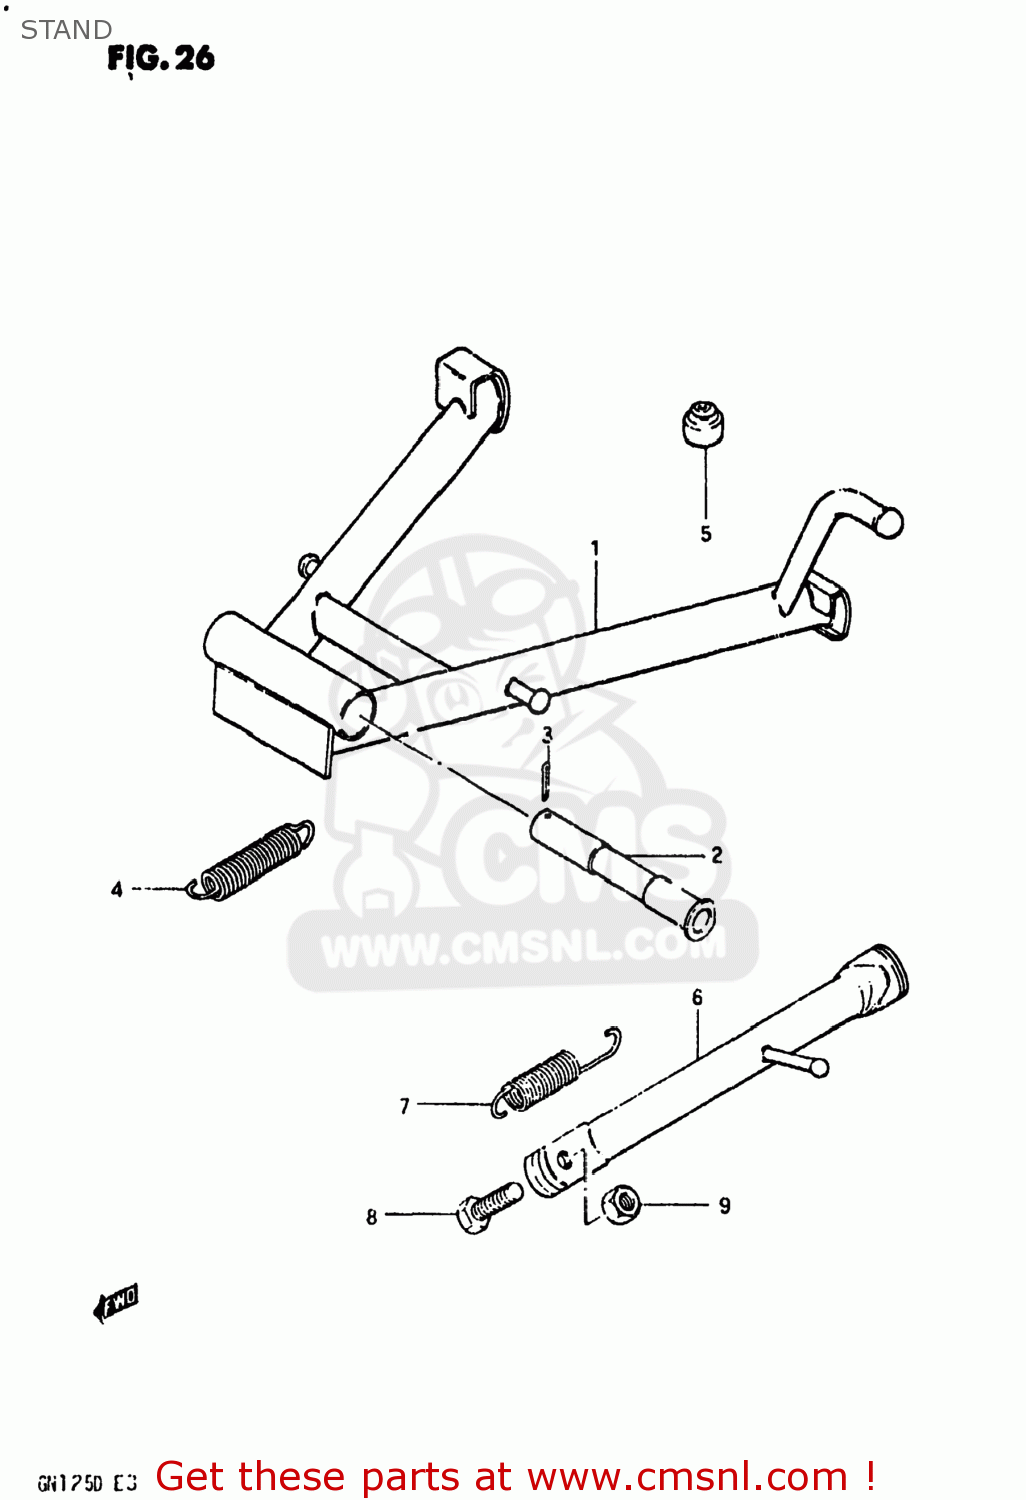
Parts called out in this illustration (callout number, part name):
1	STAND,CTR
2	SHAFT,CENTER STAND
3	COTTER PIN
4	SPRING
5	CUSHION
6	STAND,PROP
7	SPRING
8	BOLT(10X30)
9	NUT
